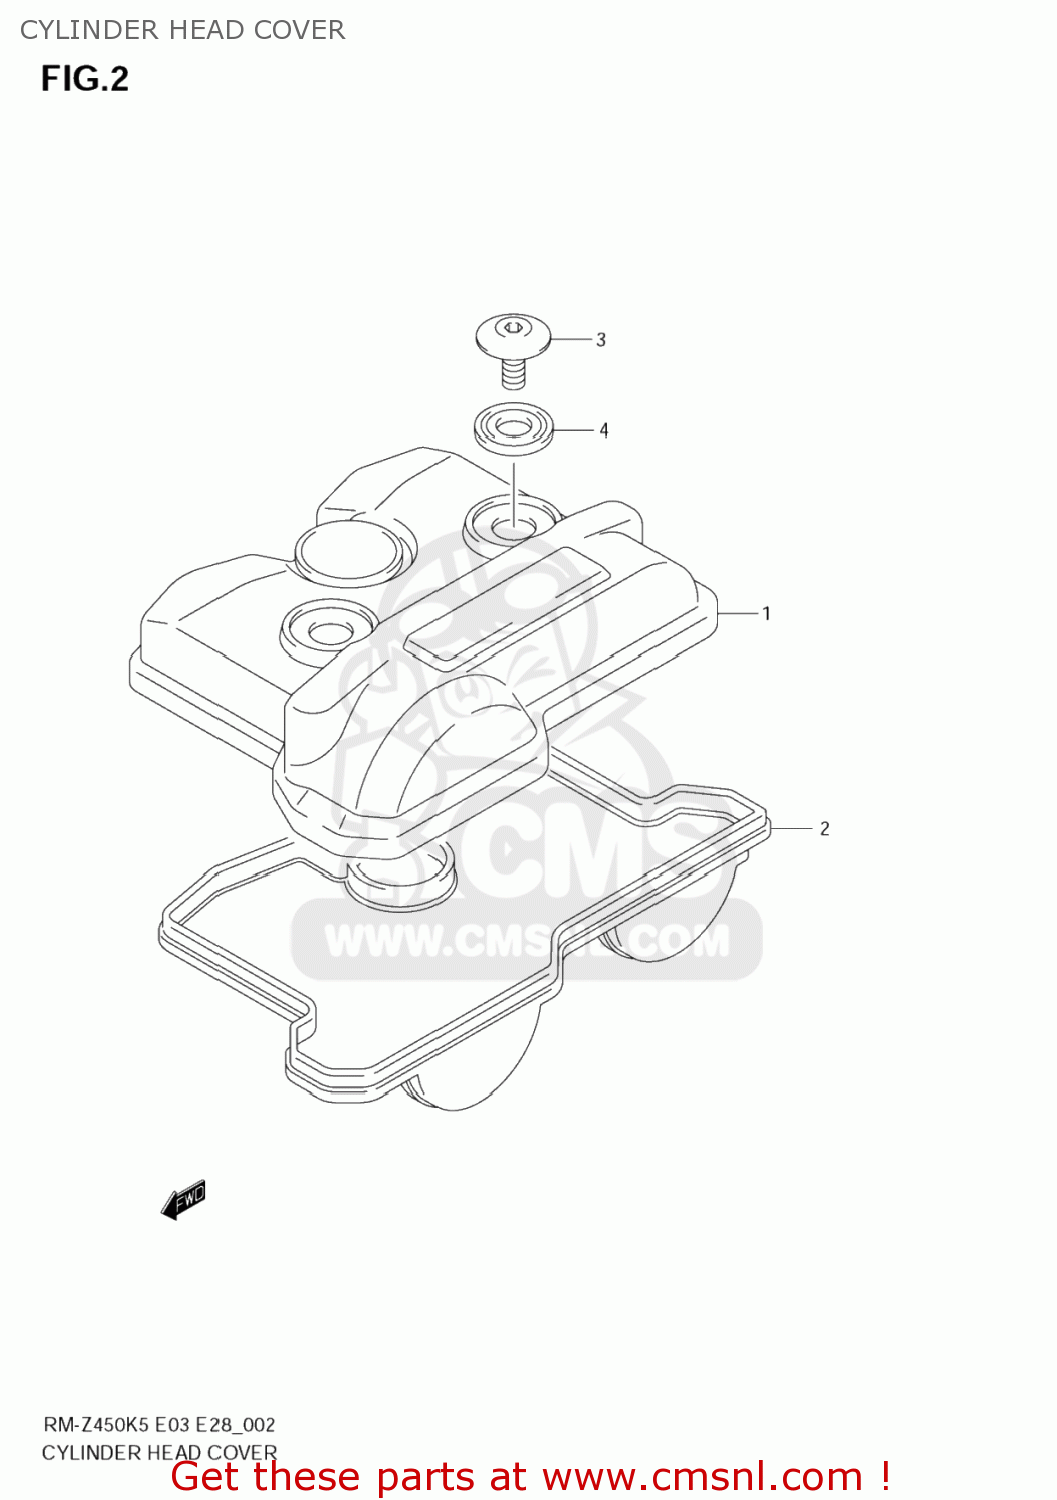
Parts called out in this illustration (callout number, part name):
1	COVER,CYLINDER HEAD
2	GASKET,CYL HEAD COVER (NAS)
3	BOLT(7X17.5)
4	WASHER(10.6X25.5X2.3)
